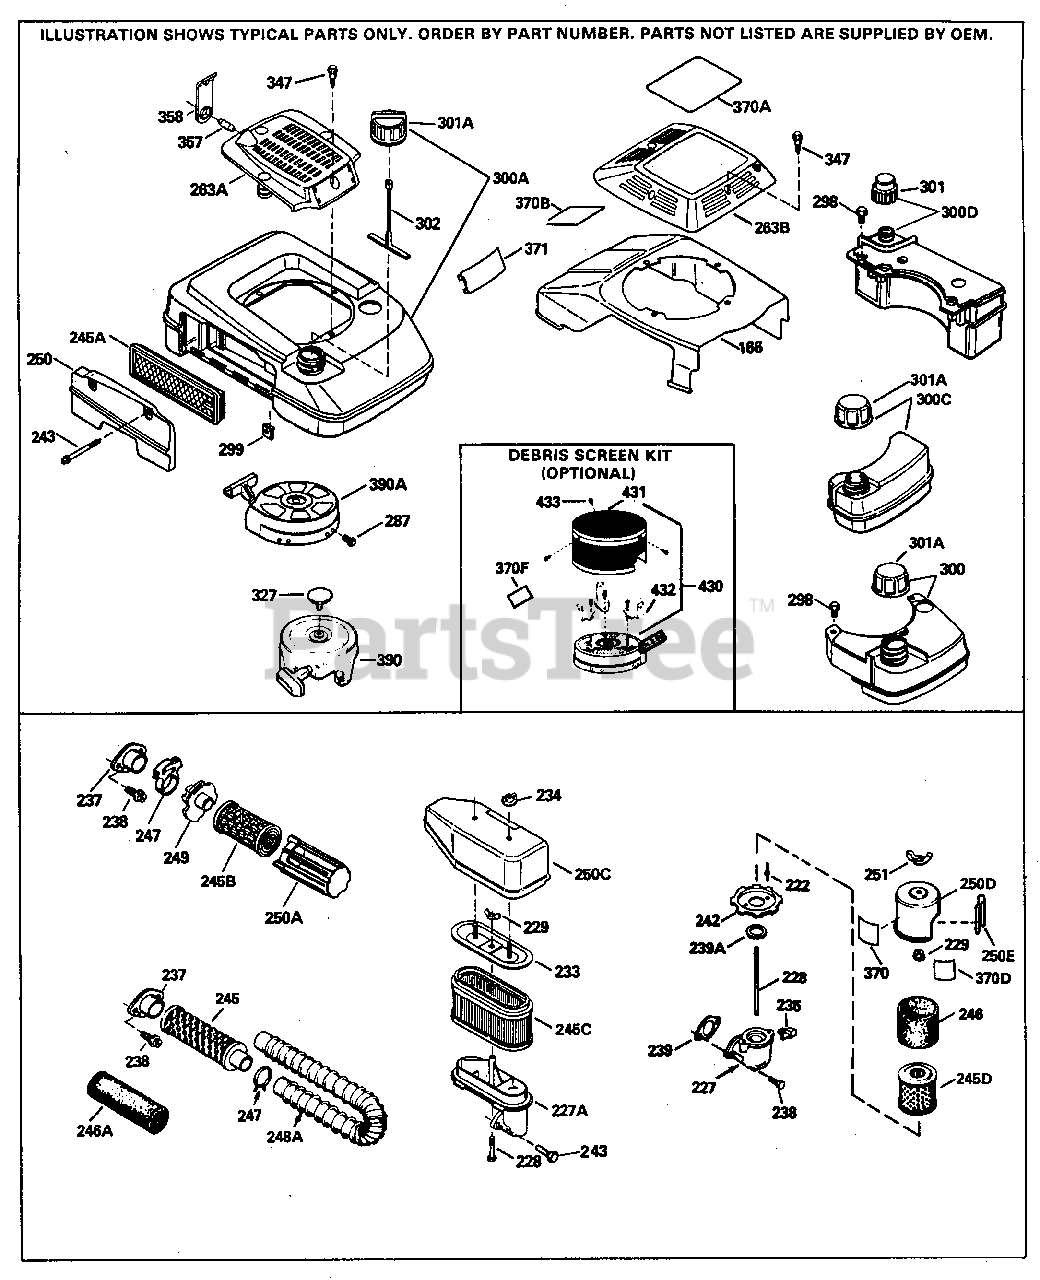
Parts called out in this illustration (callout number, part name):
237	Adapter, Air cleaner
238	Screw, 10-32 x 7/16"
239	* Gasket, Air cleaner
243	Screw, 10-32 x 2-3/32"
245A	Air Filter (also available in Package d Part #740013B)
247	Clamp, Air cleaner
287	Screw, 8-32 x 1/2"
299	Clip, "U" Type nut, 10-32
301A	Fuel Cap (Red)
327	Starter Plug
347	Screw, 10-32 x 27/32"
370F	Decal, Instruction (optional)
430	Optional Screen Kit Incl. 370F,431,43 2,433
431	Debris Screen (Optional)
432	Debris Screen Bracket (Optional)
433	Screw, 8-32 x 1/4" (Optional)
